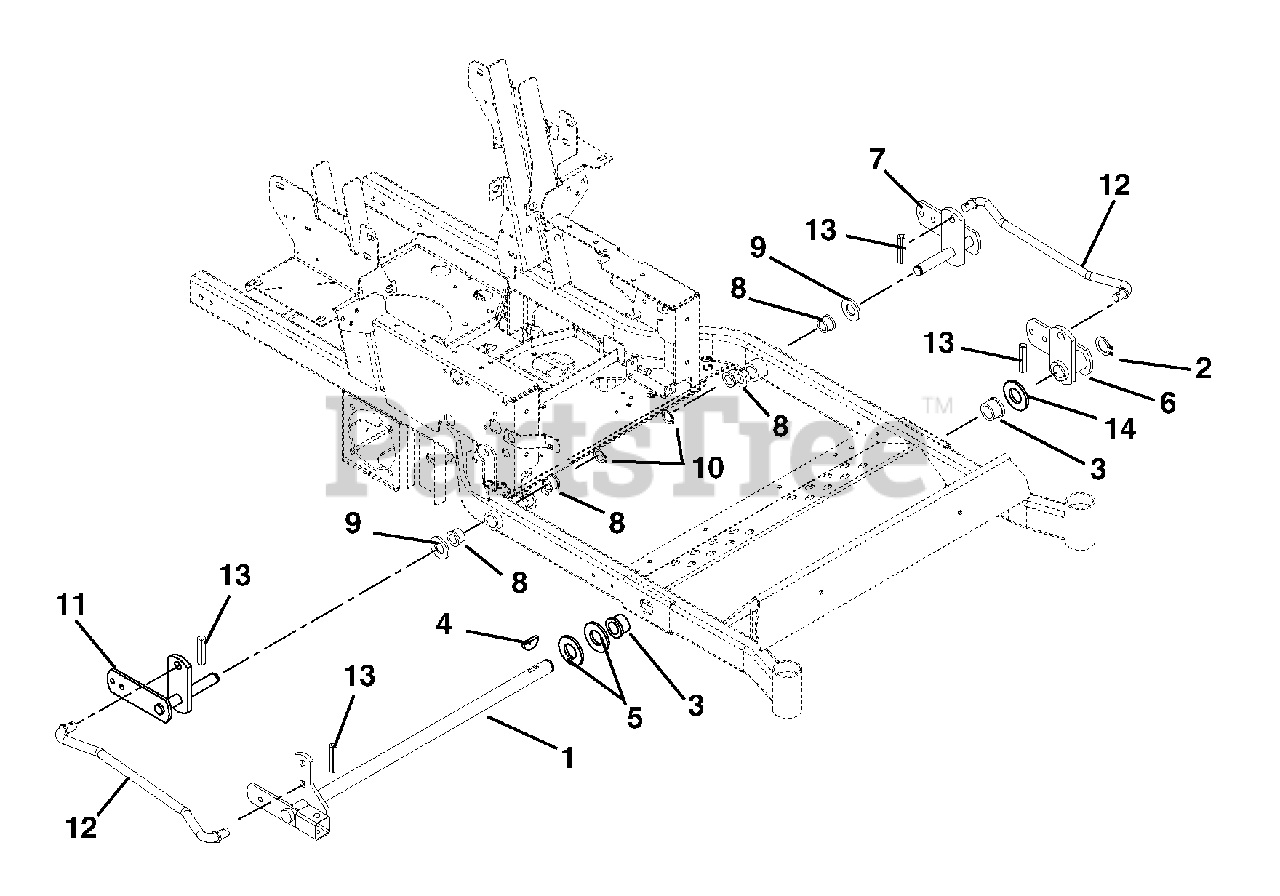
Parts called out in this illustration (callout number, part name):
1	Weldment, Lift Arm
2	Ring, Retaining External 1.00 x .078
3	Bushing, Flange Nylon 1.020 x 1.385 x .75 x 1.75
4	Key, Woodruff .25 x 1.00
5	Washer, Flat Steel 1.063 x 2.00 x .134
6	Lift Arm - Front
7	Lift Arm Shaft - Left Hand
8	Bushing, Flange Nylon .762 x 1.0 x .580 x 1.48
9	Washer, Hardened Steel .758 x 1.23 x .031
10	Ring, Retaining External .689 x .077
11	Lift Arm Shaft - Right Hand
12	Rod, Lift Assist
13	Pin, Roll .25 x 1.25
14	Washer, Hardened Thrust 1.00 x 1.55 x .03
